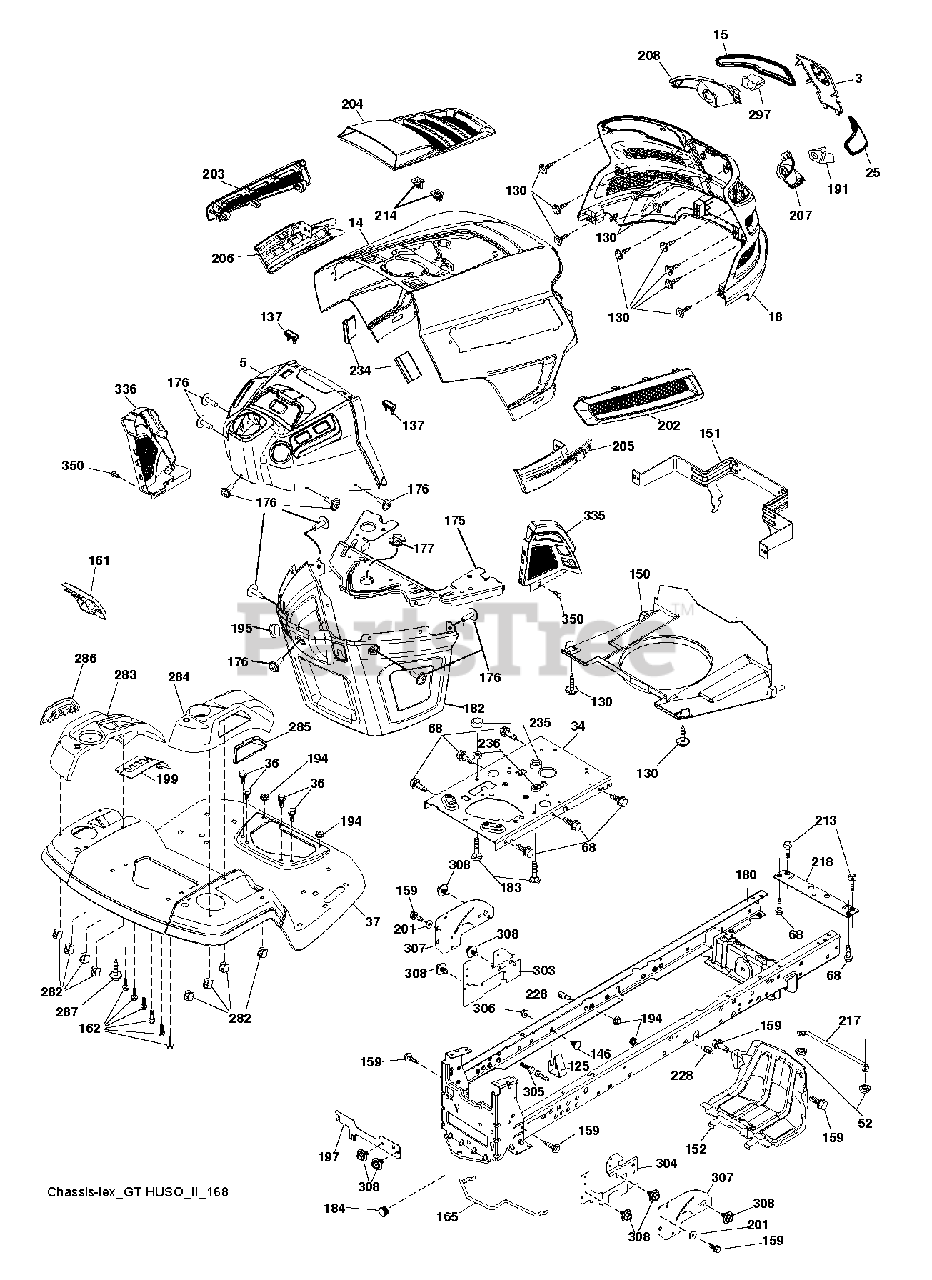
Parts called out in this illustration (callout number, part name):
3	APPLIQUE.SUBASM.GT.HUSQ.II
5	DASH.HUSQ2.SM.E.RS.HR.CHG 498
14	HOOD.ASM.HUSQVARNA.GT.TEX.ORAN
15	LENS.HEADLIGHT.LH.GTII.2011
18	GRILLE.SUBSTRATE.2011.
25	LENS.HEADLIGHT.RH.GTII.2011
34	PLATE.ENGINE.WELDED.CHASSIS
36	SCREW 5/16"
37	FENDER.TLT.FS.W/CPH.W/FW.668
52	LOCKNUT
68	SCREW LT
125	CLIP.FUEL.LINE
130	SCREW.#10 X 0.750.BOS
137	BUMPER DASH
146	BOLT.RDHD.SHT.SQNK.3/8-16X5/8
150	AIR.DUCT.GTV.BLACK
151	BRACKET.PIVOT.HOOD.GT.HUSQ.II
152	SHIELD.BROWNING.PNT.GT.V2
159	SCREW, 3/8-16X3/4
161	WINDOW.FUEL.LT.TEX.GREY
162	SCREW.HI-LO.CONSOLE
165	SUPPORT.TANK.REAR.W/TEX
175	PLATE.CROSSMEMBER.HUSQ
176	SCREW.#10-24X5/8.RN.QU
177	BUSHING, STEERING
180	CHASSIS
182	DASH LOWER.HUSQ.PRED NO CRUISE
183	BOLT.5/16-18X1-1/4 FULL THD
184	PLUG.DEMO.625
191	INSERT.REFLECTIVE.RH.HUSQ.GTII
194	NUT LOCK HEX FLANGE 5/16-18
195	PLUG.HOLE.DASH.LOWER.12V.BLK
197	SHIELD.DRWBAR.LT.RTANK.431
199	PLATE.DECK.LIFT.HUSQ.LT
201	WASHER
202	VENT.SIDE.RH.GT.HUSQ.II.
203	VENT.SIDE.LH.GT.HUSQ.II.498
204	VENT.TOP.HUSQ.GT2
205	SIDE.TRIM.RH.GT.HUSQ.II
206	SIDE.TRIM.LH.GT.HUSQ.II.GRAY
207	BEZEL LIGHT.RH.GT.II.MYLAR
208	BEZEL LIGHT.LH.GT.II.MYLAR
213	BOLT
214	CLIP.RETAINER.TINNER.
217	ROD.PIVOT.HOOD
218	X-PIECE.HOOD.STOP.NON/
228	STUD.FASTNER.W/ANTI-ROTATE
234	BUMPER.HOOD.TEX.HUSQVARNA
235	SPACER FENDER
236	NUT.CENTERLOCK.5/16-
282	CLIP.RETAINER.CONSOLE.LT.HUSQ
283	CONSOLE.ASM.LFT.RSF.HUSQ.LT
284	CONCOLE.CNTRL.PDL.HUSQ.LT.498
285	CONSOLE INSERT RH
286	CONSOLE.INSRT.LH.HUSQ.LT.BLACK
287	SCREW 1/4X20
297	INSERT.REFLECTIVE.LH.HUSQ.GTII
303	SHIELD.LOWER.LH/LT/GT/BLK.EDIP
304	SHIELD.LWR.RH.LT30DECK.PNT.BLK
306	NUT LOCK FLG 3/8-16 UNC
307	SHIELD.UPPER.LT.GT.ISO
308	BOLT, 5/16-18 X 1 3/4
335	COVER.LOWER.DASH.RH.BLACK
336	COVER-LH.LOWER.DASH.GT2.BLACK
350	CLIP.X-MAS.TREE
